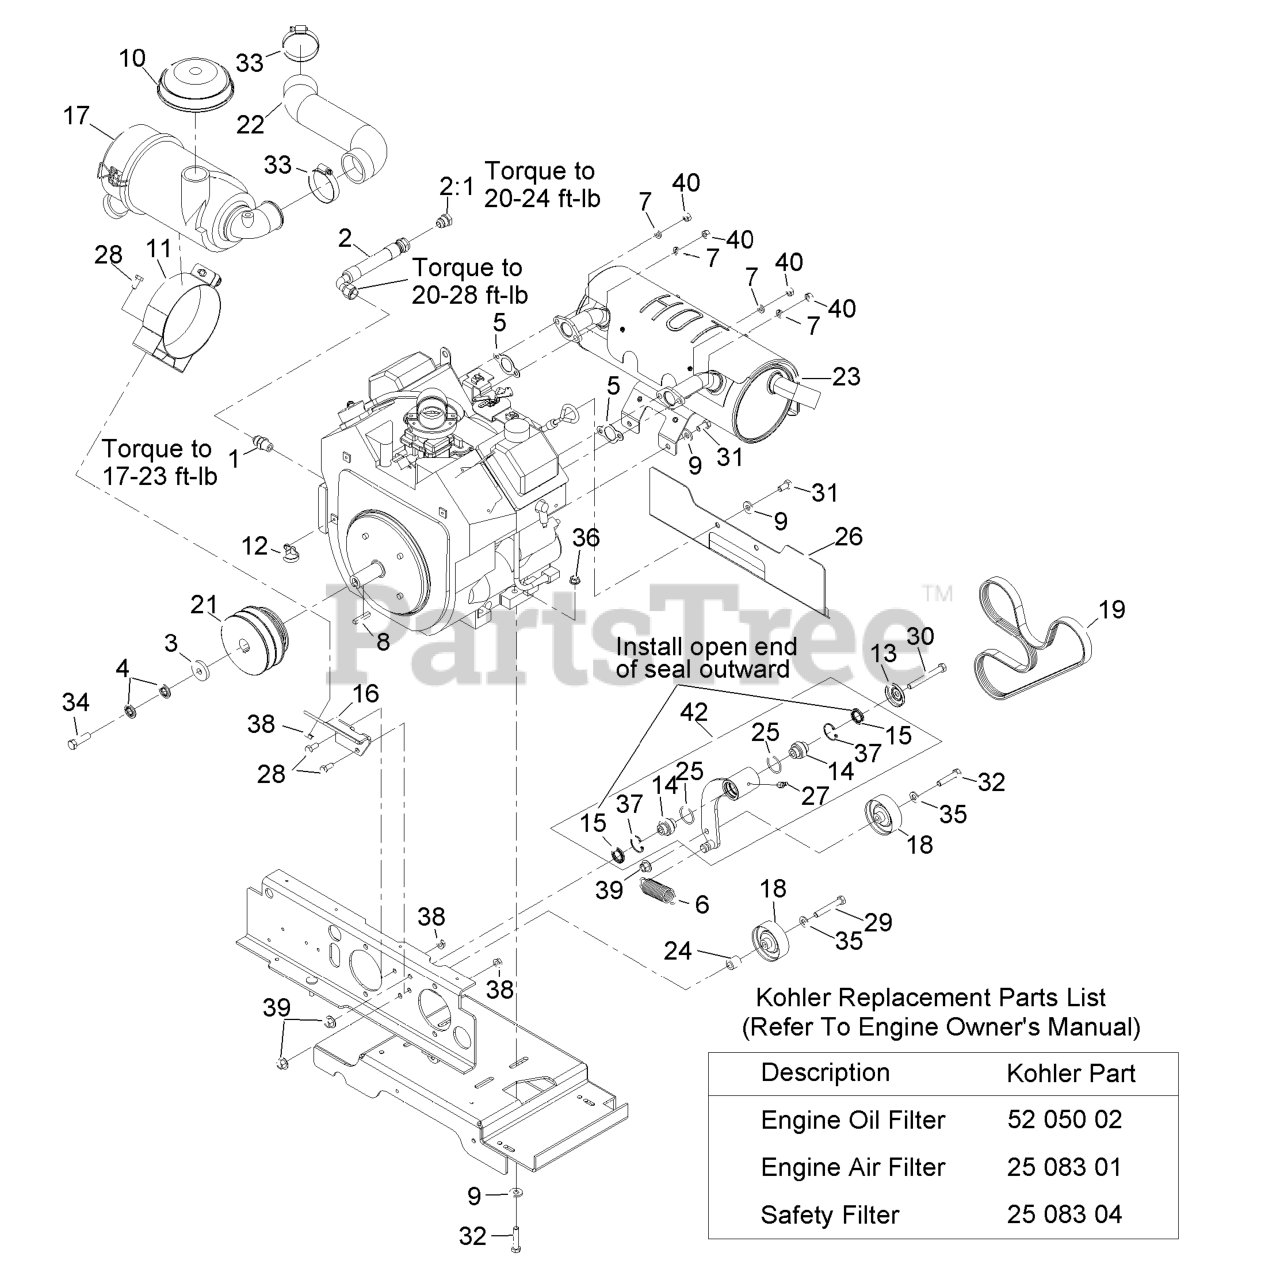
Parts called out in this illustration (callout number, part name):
1	FITTING-STRAIGHT
3	WASHER-CLUTCH
4	WASHER-SPRING
5	GASKET (KOHLER)
6	SPRING-IDLER
7	WASHER-LOCK
8	KEY-SQUARE
9	WASHER-BELLEVILLE
10	HOOD-CLEANER, 2" AIR INTA
11	BRACKET-FILTER, AIR
12	Tie-Cable
13	GUARD-TOP
14	BEARING-SPHERICAL
15	SEAL-LIP, SINGLE
16	BRACKET-FILTER, AIR
17	AIR CLEANER CANISTER ASM
22	HOSE-AIR INTAKE
24	SPACER-MOUNTING, STEERING
26	SHIELD-EXHAUST
27	FITTING-LUBE, 45 DEG
28	SCREW-HH
29	BOLT-CARR
30	SCREW-HH
31	SCREW-HH
32	SCREW-HH
33	CLAMP-HOSE
34	SCREW-HH
35	WASHER-FLAT
36	NUT-HHF, WHIZ
37	RING-SNAP
39	NUT-FLANGE
40	NUT-HEX
42	IDLER ASM
